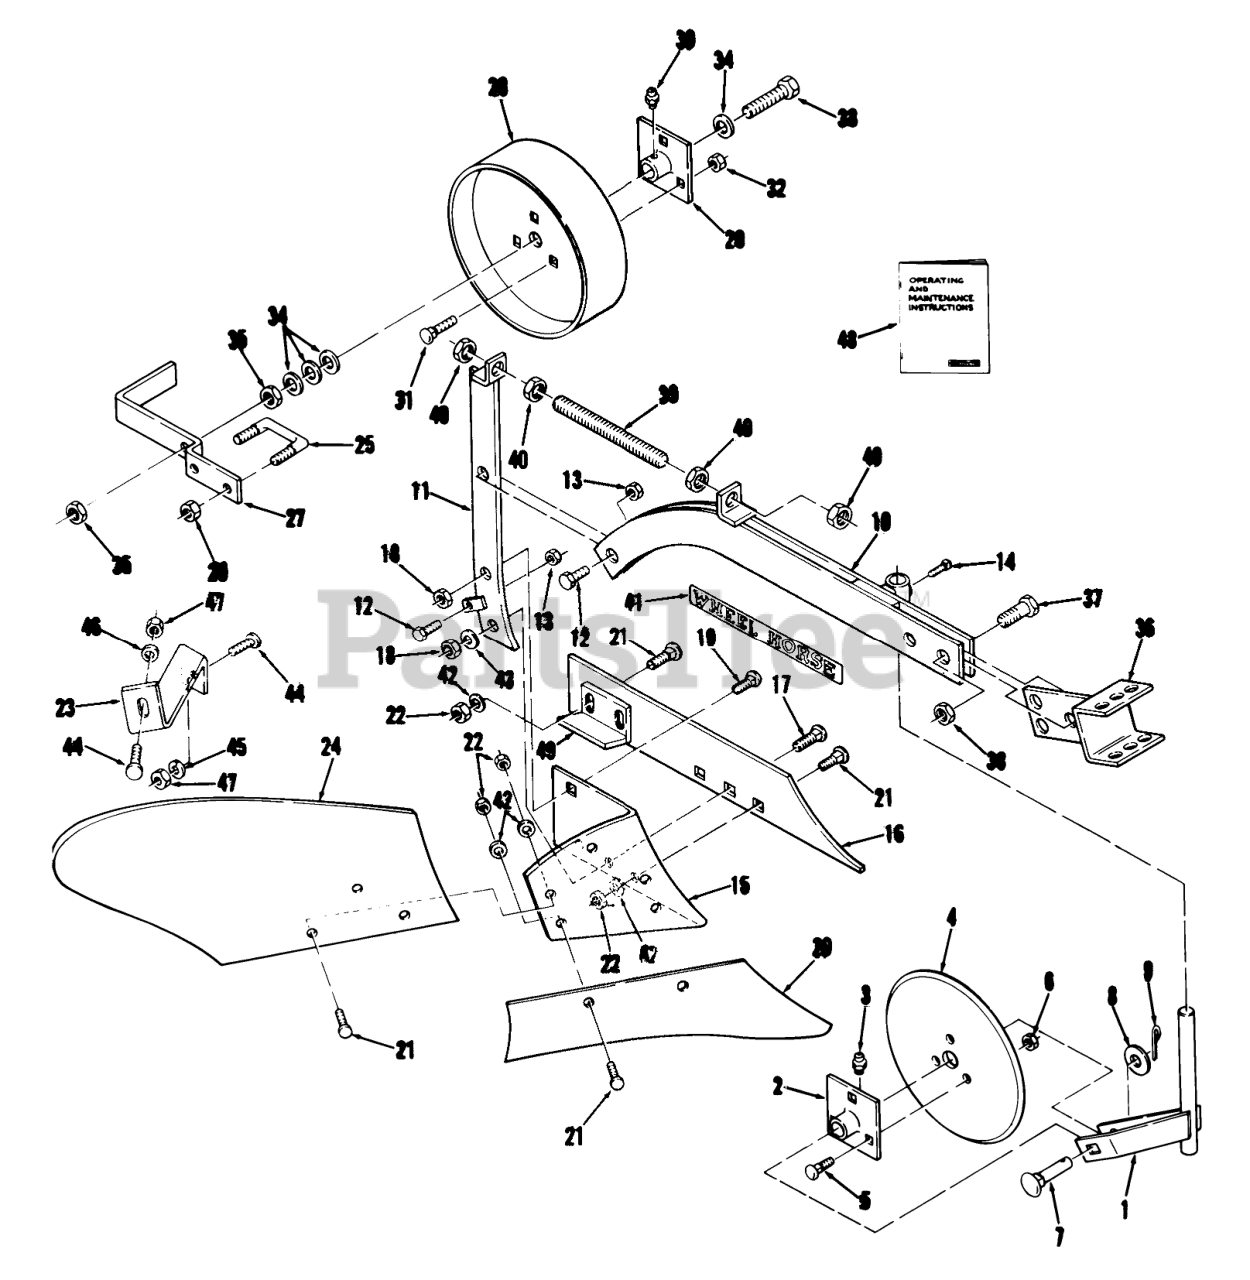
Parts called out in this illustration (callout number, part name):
1	Fork Assembly
2	Hub Assembly
3	Grease Fitting
4	Coulter Blade
5	Bolt
6	Nut
7	BOLT-CARR BLANK
8	Washer 5/8 U.S.
9	Cotter Pin
10	Beam Assembly
11	Standard Assembly
12	H H C S
13	Eslok Nut
14	Screw-Set
15	12" Landslide
17	Plow Bolt 1/2-13 x 2
18	Eslok Nut
19	CARRIAGE BOLT -4
21	12" Share
21	Plow Bolt 7/16-14 x 1 1/4
22	Nut
23	Brace
23	12" Mold Board
25	Special "U" Bolt
26	E.S. Nut 5/8-11
27	Gage Wheel Brace
28	Gage Wheel Assembly
29	Hub Assembly
30	Grease Fitting
31	Bolt
32	Nut
33	Hex Bolt 5/8-11 x 4 1/2
34	Washer 5/8 U.S.
35	Jam Nut 5/8-11
36	Yoke Assembly
37	Bolt
40	Jam Nut 5/8-11
41	DECAL-WHEEL HORSE
42	WASHER
43	Washer
44	Plow Bolt 7/16-14 x 1 1/4
45	LOCKWASHER
46	WASHER
47	Nut
48	Operating and Maintenance Instructions
49	Bracket
